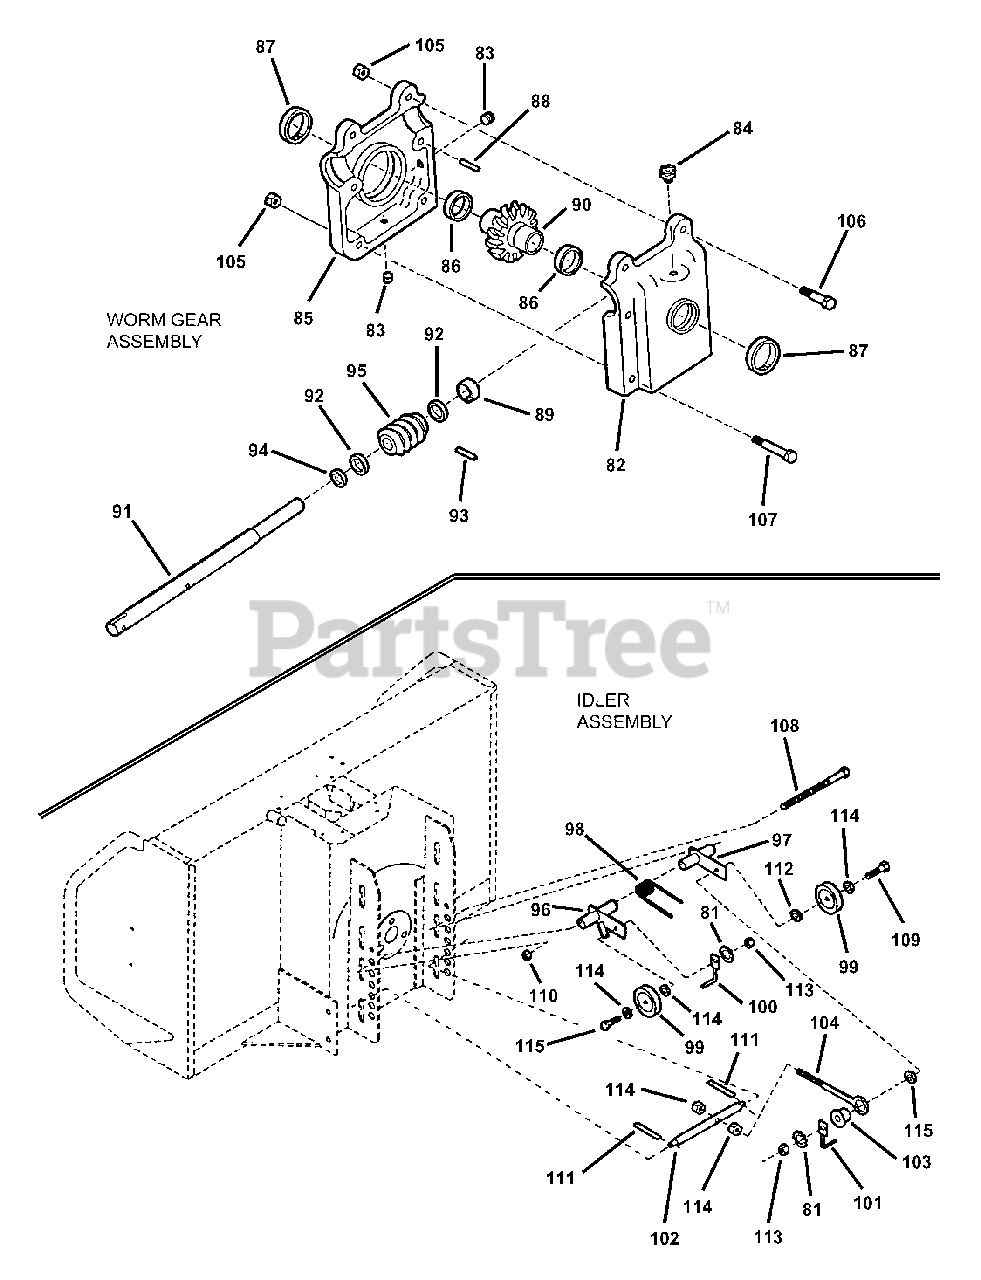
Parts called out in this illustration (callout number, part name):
81	WASHER, 3/8" Internal Tooth Lock
82	CASING, Right Hand
83	PLUG, 1/8" NPT
84	BREATHER, 1/8" NPT 5 PSI
85	CASING, Left Hand
86	BEARING
88	PIN, 3/16 x 1/2" Long Dowel
89	FROST CAP
90	BRASS GEAR, 8 DP 4 LH
91	INPUT SHAFT
92	BEARING
93	PIN, 5/16 x 1-1/4" Long Spring
95	WORM, 8 DP 4 LH
96	BRACKET, Left Idler
97	BRACKET, Right Idler
99	PULLEY, Idler
100	BELT GUIDE (short bend)
101	BELT GUIDE (long bend)
102	TENSION ROD
104	EYE BOLT, 5/16-18 x 5"
105	NUT, 5/16-18 Hex Lock
106	BOLT, 5/16-18 x 1-3/4" Hex
107	BOLT, 5/16-18 x 2-1/4" Hex
108	BOLT, 1/2-13 x 8" Hex
109	BOLT, 3/8-16 x 2-3/4" Hex
110	NUT, 1/2-13 Hex Nyloc
111	PIN, 1/8 x 1-1/4" Cotter
112	WASHER, 7/16" Flat
113	NUT, 3/8-16 Hex
114	NUT, 5/16-18 Hex Nyloc
115	BOLT, 3/8-16 x 2-1/4" Hex
